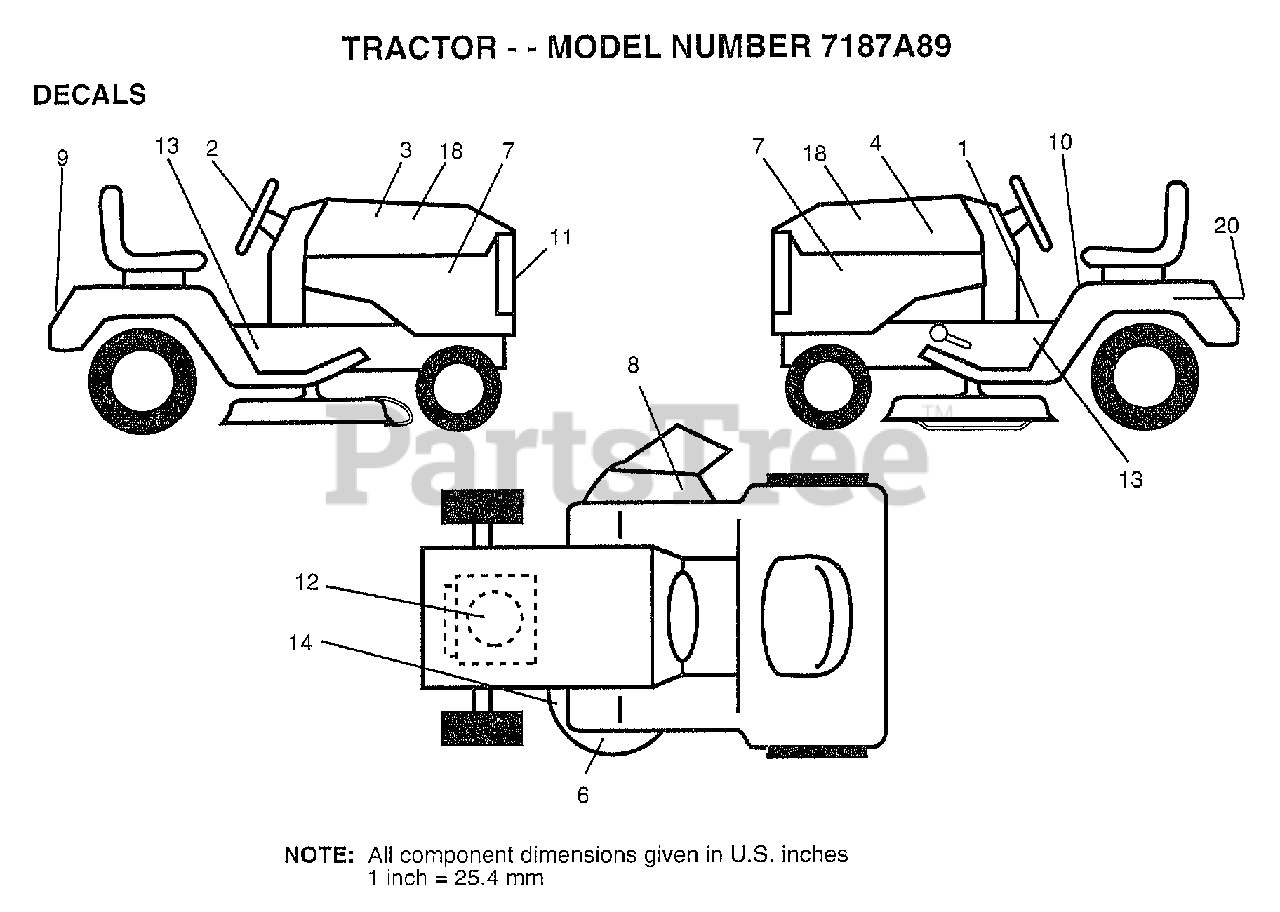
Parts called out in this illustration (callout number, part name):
1	"DECAL-DASH,OPER"
2	DECAL STEER WHL
3	DECAL HOOD RH
4	DECAL HOOD LH
6	DECAL DECK MULCH
7	DECAL PANEL SIDE
8	DECAL DECK WIZ +
10	"DECAL DANGER,FEND"
11	DECAL.LENS.WIZARD
12	DECAL, ENGINE
13	DECAL CHASSIS WIZ
14	"DECAL-SCHEM,BELT"
18	NAMEPLATE.HD.WIZA
20	DECAL.BATRY.3-3908
